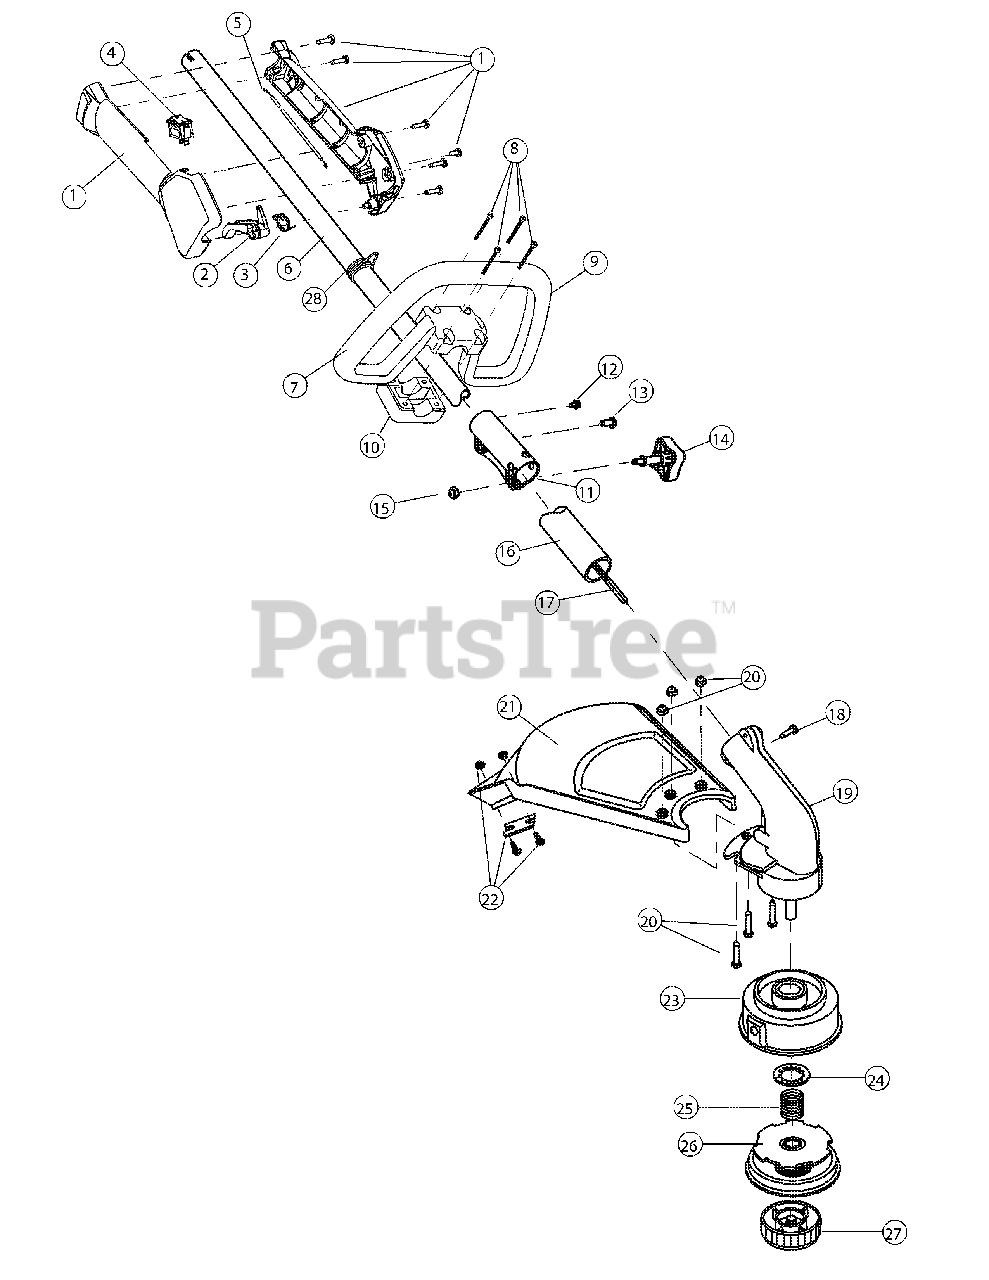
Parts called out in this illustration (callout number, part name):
1	Throttle Housing Assembly
2	Throttle Trigger
3	Throttle Trigger Spring
5	Throttle Cable Assembly
6	Upper Drive Shaft Housing Assembly
7	Deluxe D-Handle Assembly
9	Deluxe D-Handle
10	Bottom Clamp
11	Split Boom Coupler
14	Adjustment Knob
15	Knob Retaining Nut
16	Lower Drive Shaft Housing Assembly
17	Lower Flexible Drive Shaft
18	Anti-Rotation Screw
19	Gear Box Assembly
20	Shield Mounting Hardware
21	Shield Assembly
22	Blade Assembly
23	Outer Spool Assembly
26	Inner Reel
27	Bump Head Knob Assembly
28	Shoulder Strap Clip
